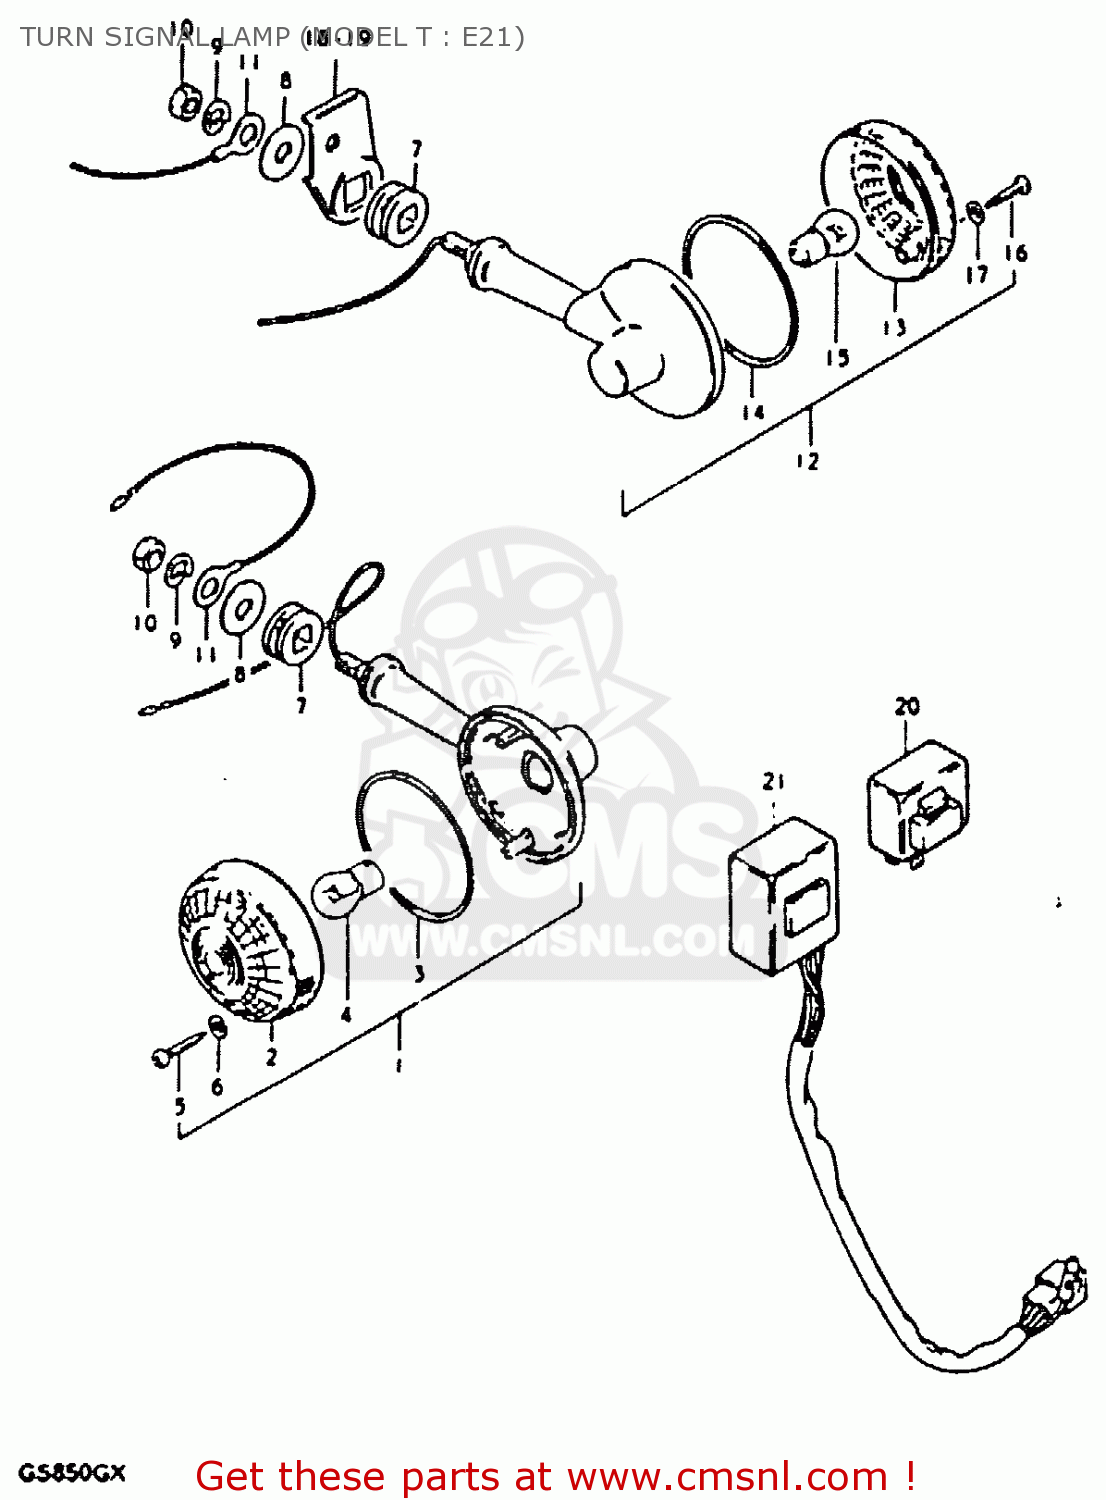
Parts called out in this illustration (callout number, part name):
1	LAMP ASSY, FRONT TURN SIGNAL
2	LENS
3	GASKET (NAS)
4	BULB 12V 21W
5	BOLT
6	GASKET (NAS)
7	CUSHION
8	WASHER
9	LOCK WASHER
10	NUT
11	LEAD WIRE,EARTH
12	LAMP ASSY, REAR TURN SIGNAL
13	LENS
14	GASKET (NAS)
15	BULB 12V 21W
16	BOLT
17	GASKET (NAS)
18	BRACKET,RR TURNSIGNAL LAMP,R
19	BRACKET,RR TURNSIGNAL LAMP,L
20	RELAY,TURN SIGNAL
21	UNIT,TURN SIGNAL CONTROL
